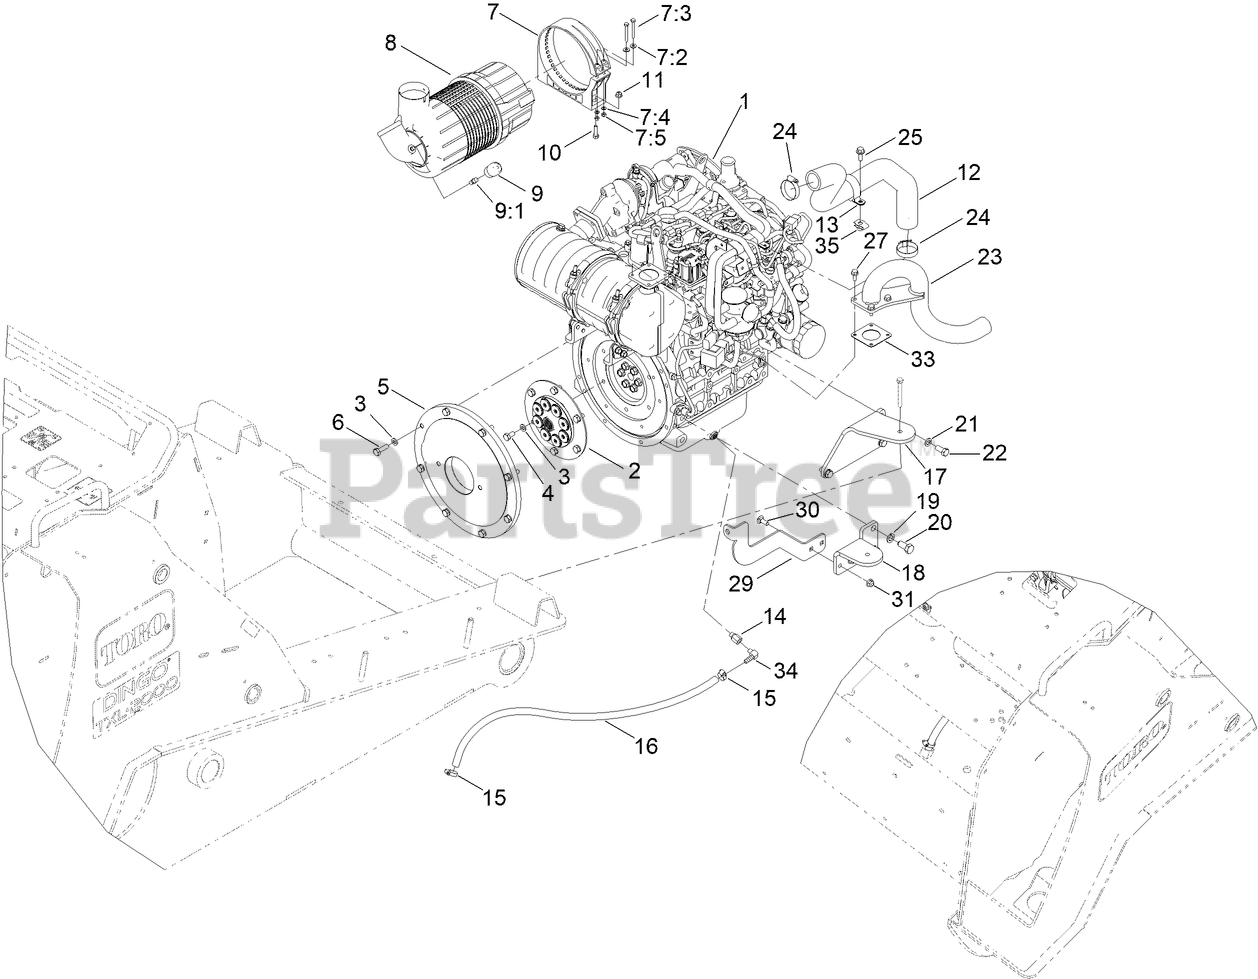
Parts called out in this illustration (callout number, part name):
1	ENGINE-KUBOTA
2	COUPLER-SPRING, FLYWHEEL
3	WASHER-HARDENED
5	PLATE-FLYWHEEL
6	SCREW-HH
7	STRAP-CLEANER, AIR
7:2	WASHER-FLAT
7:3	SCREW-HH
7:4	WASHER-FLAT
7:5	NUT-LOCK
8	AIR CLEANER ASM
9	INDICATOR
9:1	ADAPTER-INDICATOR
10	SCREW-HH
11	NUT-HF, NI
12	HOSE-AIR, COOLER
13	CLAMP-R
14	ADAPTER-DRAIN
15	CLAMP-HOSE
16	HOSE-DRAIN
17	MOUNT-ENGINE
18	MOUNT-ENGINE
19	WASHER-LOCK, SPRING
20	SCREW-HH
21	WASHER-LOCK
22	SCREW-HH
23	PIPE-EXHAUST
24	CLAMP-HOSE
25	SCREW-HHF
27	SCREW-HHF
29	BRACKET-PUMP, RH
30	BOLT-CARR
31	NUT-HF, NI
33	GASKET-MUFFLER
34	FITTING-90 DEG
35	NUT-TINNERMAN
